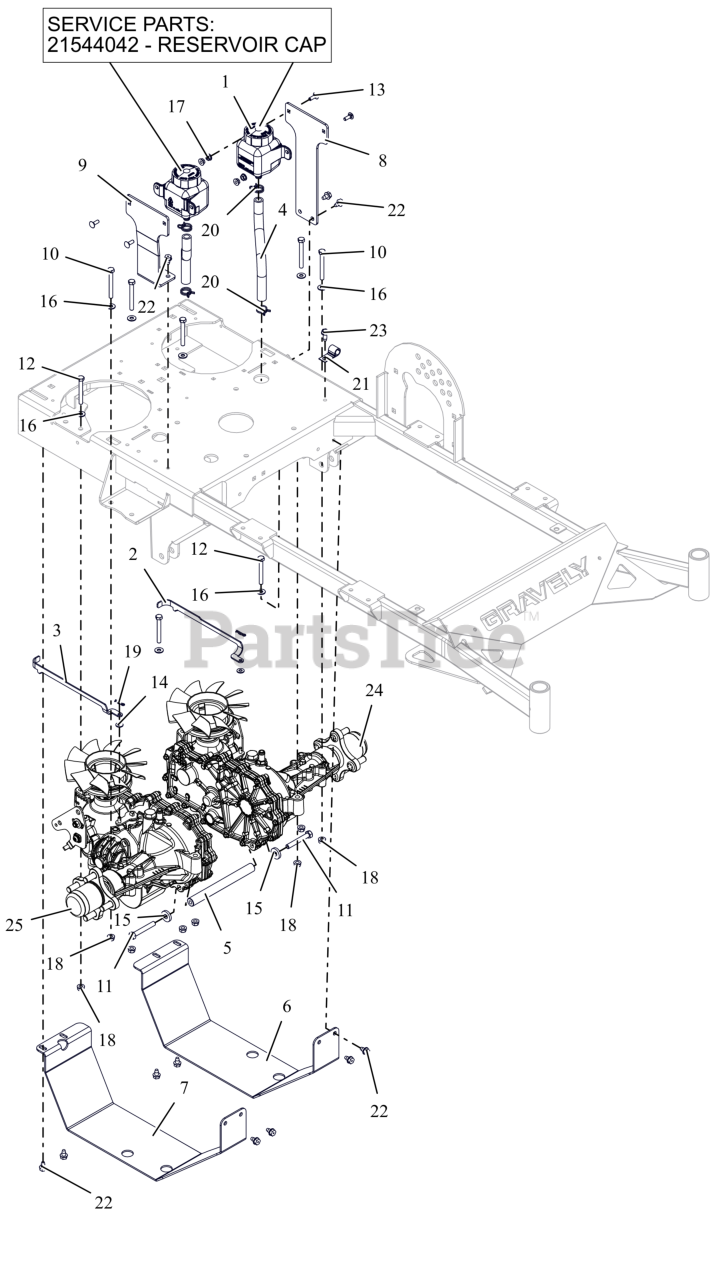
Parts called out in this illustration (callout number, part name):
1	TANK, EXPANSION
1	CAP, HYDRO RESERVOIR REPLAC.
2	BRKT, LH DUMP VALVE (BLACK)
3	BRKT, RH DUMP VALVE (BLACK)
4	HOSE, PRO WALK OVERFLOW
5	SHAFT, CROSS
6	PLATE, LH 36" SKID (BLACK)
7	PLATE, RH 36" SKID (BLACK)
8	BRKT, EXPANSION TANK MTG (RED)
9	BRKT, EXPANSION TANK MTG
10	BLT, HEX .31-18X2.75 G5 ZCC
11	BLT, HEX .38-16X2.50 G5 ZCC
12	BLT, HEX 0.3125-18X2.5 GR5 ZCC
13	BLT, RHSN .25-20X.750 G5 ZCC
14	WSHR,FLT .281X.625X.065 ZCC
15	WSHR, FLT .406X1.00X.188 ZCC
16	WSHR, FLT .312X.734X.065 ZCC
17	NUT-LK-CTR-FLG .25-20 ZC120
18	NUT,LK-CTR-FLG .31-18 GF ZCC
19	PIN, HAIR #225 .072X1.09
20	3/4 WIRE HOSE CLMP ZC
22	SCR,TAP .312-18X.50 HWH TR ZCC
23	SCR,TAP .312-18X.75 HWH TR ZCC
24	TRANSAXLE, ZT2800 - LH
25	TRANSAXLE, ZT2800 - RH
